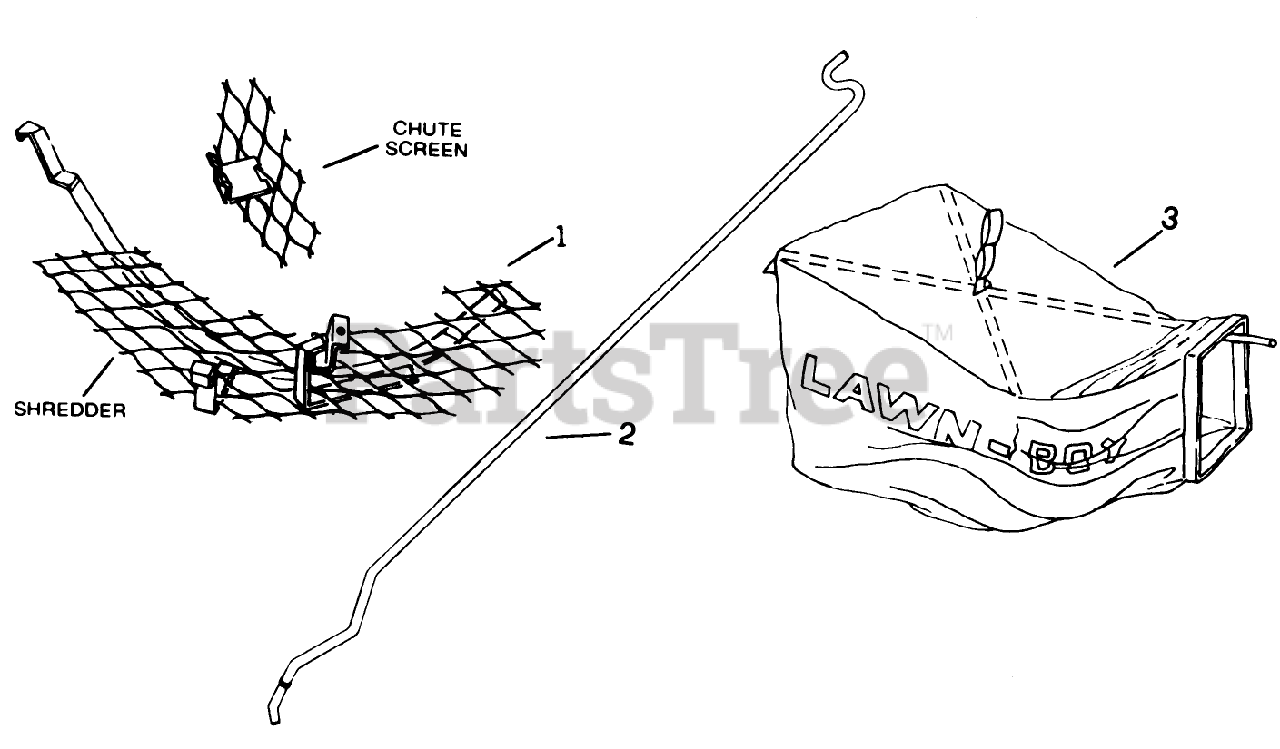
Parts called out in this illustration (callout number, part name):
1	21" Leaf Shredder Kit
2	ROD GRASSBAG
3	Leaf Bag
